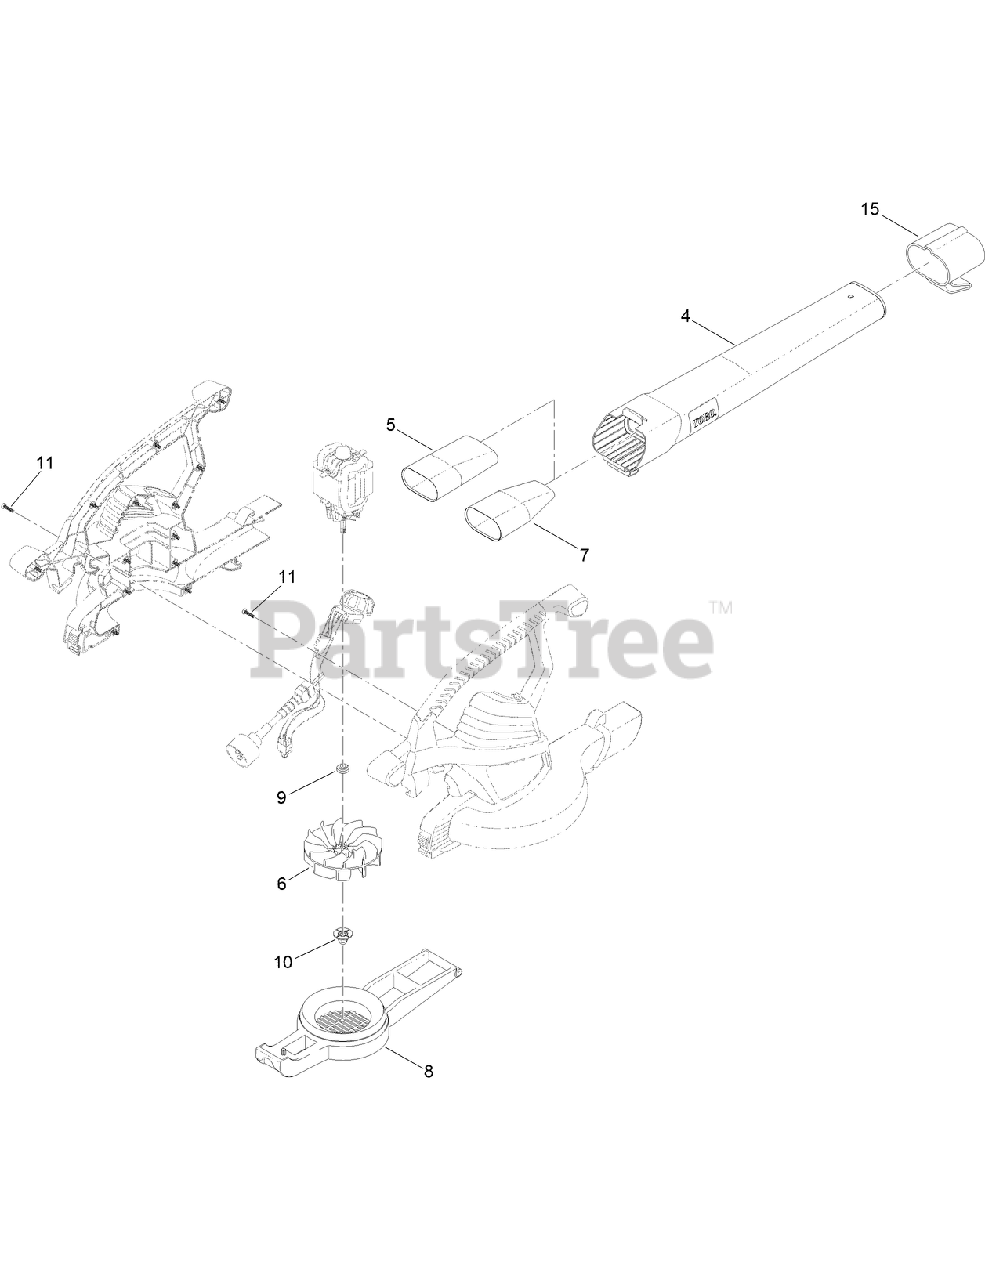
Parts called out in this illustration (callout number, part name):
4	TUBE-BLOWER
5	TUBE-INSERT
6	IMPELLER ASM
7	INSERT-TUBE, MPH
8	COVER-INLET
9	BUSHING-MOTOR
10	NUT-IMPELLER
11	SCREW-PPH
15	ADAPTER-WRAP, CORD
